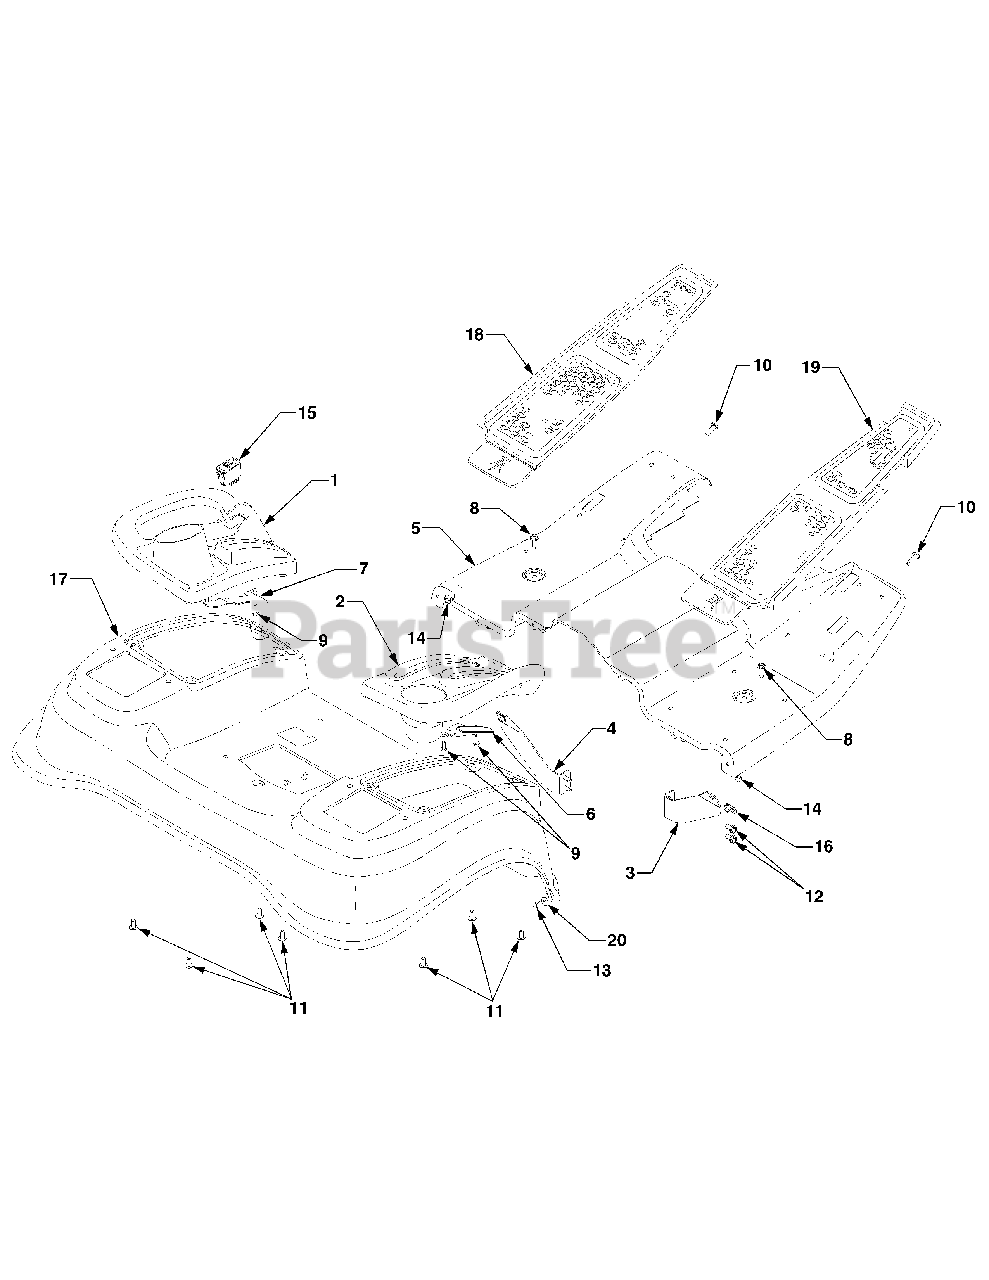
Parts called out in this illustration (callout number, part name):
1	Cover, Fender, LH
2	Cover, Fender, RH
3	Bracket, Running Brd Mtg. RH
4	Bracket, Running Brd Mtg. LH
5	Running Board
9	Screw, Hex Wash. Hd, Tapp 1/4-15 x .75
10	Screw, Pan Hd. 5/16-18 x 1.0 ..
11	Screw, Truss Phillips Hd. 5/16-14 x .75
12	Screw, Hex Wash. Hd. Tapp 5/16-18 x .75
13	Screw, Hx. Cap, 1/4-20 x .5 GR5
14	Nut, Hx. Insert Lck, 1/4-20 GR8
15	Switch, PTO Reverse
16	Nut, Speed, 5/16-18
17	Fender
17	Graphic, Power Shaft
17	Graphic, Warning
17	Graphic, 4WD
18	Pad, Floor - LH
19	Pad, Floor - RH
20	Washer, Flat, .26 x .72 x .06
